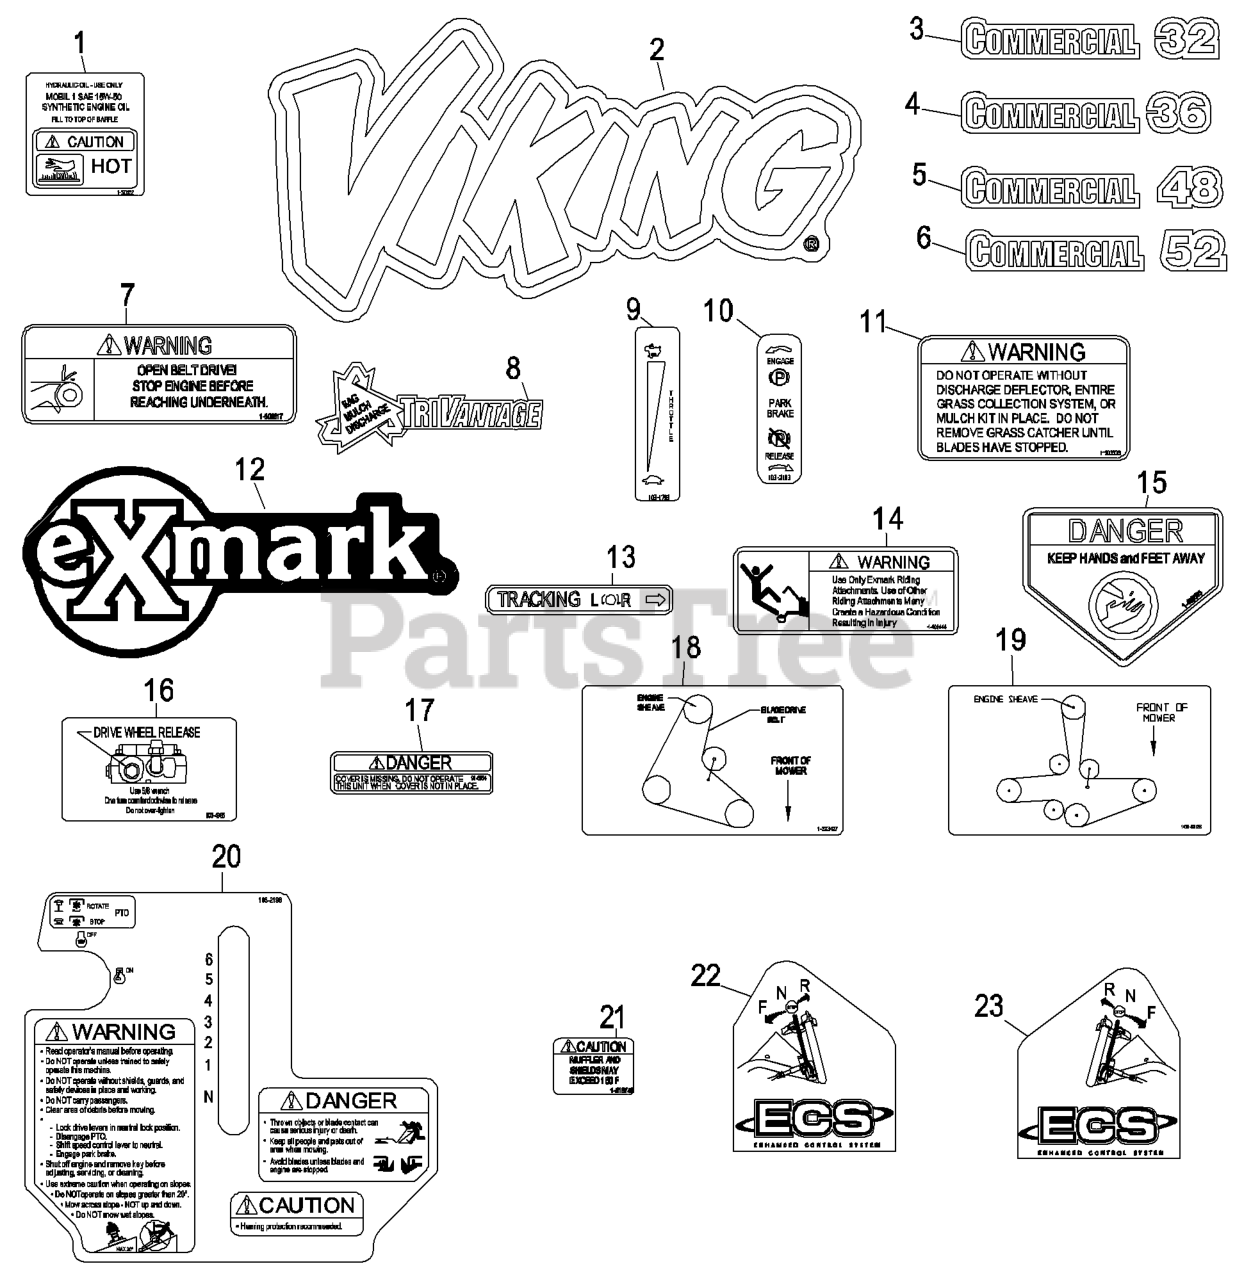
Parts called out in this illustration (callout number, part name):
2	DECAL,VH MODEL
3	DECAL,COMMERCIAL 32
4	DECAL,COMMERCIAL 36
5	DECAL,COMMERCIAL 48
6	DECAL,COMMERCIAL 52
7	DECAL,BELT DRIVE
9	DECAL,THROTTLE ONLY
10	DECAL-BRAKE, PARK
11	DECAL-WARNING, DISCHARGE
12	DECAL,EXMARK LOGO
13	DECAL,TRACKING ADJUST
14	DECAL,SULKY WARNING
15	DECAL-DANGER
16	DECAL,DRIVE RELEASE
17	DECAL-COVER, MISSING
18	DECAL,BELT ROUTING 32/36
19	DECAL,BELT ROUTING
20	DECAL,CONSOLE VH ECS
22	DECAL,LH ECS INSTRUCTION
23	DECAL,RH ECS INSTRUCTION
